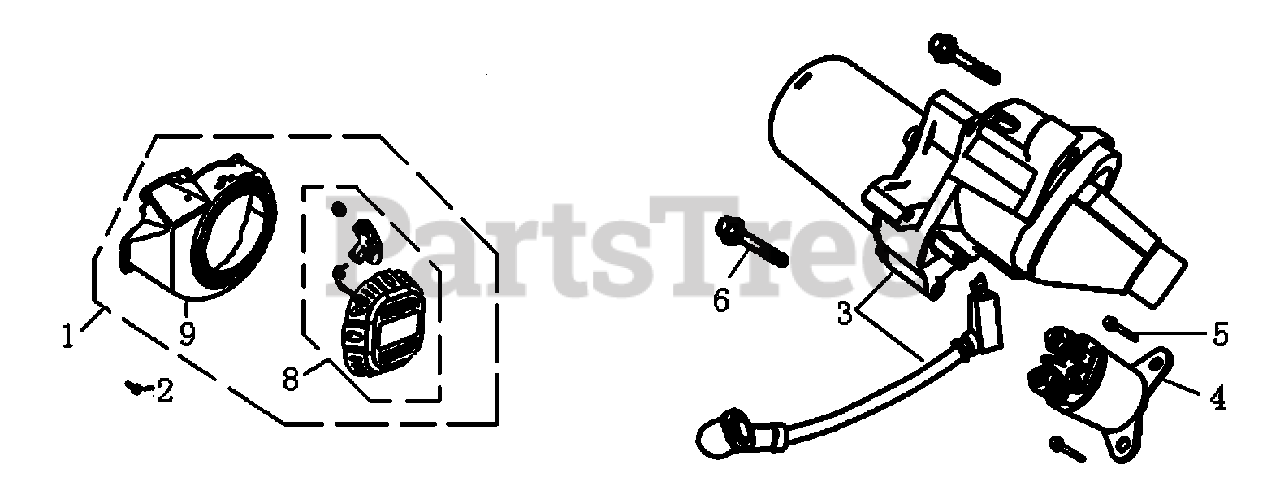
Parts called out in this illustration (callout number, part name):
1	RECOIL W/ HSNG ASSY.
2	BOLT, FLANGE
3	MOTOR, STARTER
4	CONTACTOR ASSY.
5	BOLT-WASHER
6	BOLT, FLANGE
8	RECOIL ASSY.
9	BLOWER HOUSING
